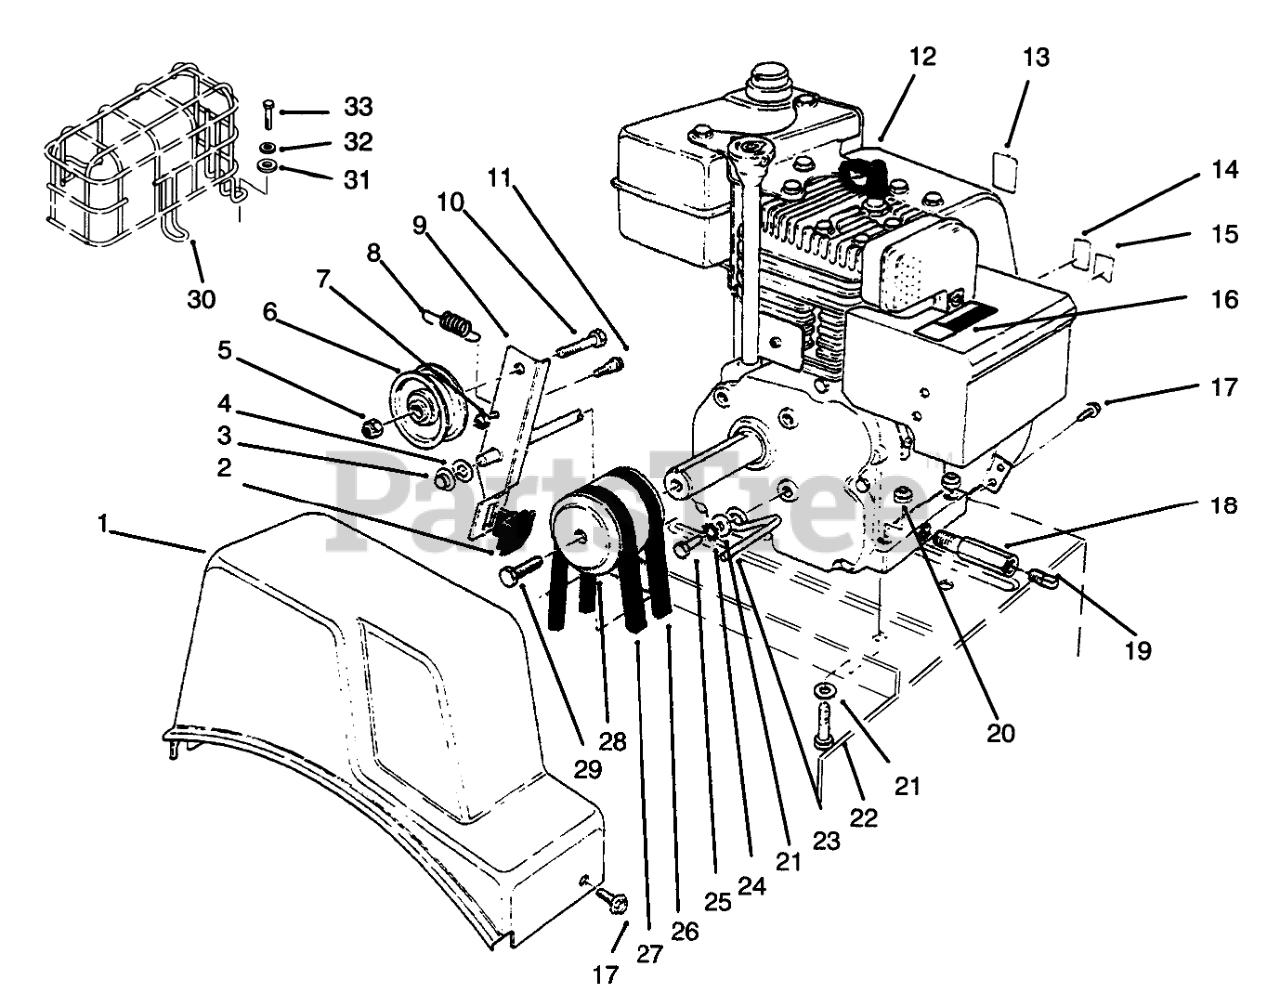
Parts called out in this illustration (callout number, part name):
1	COVER-BELT
2	PAD-BRAKE
3	NUT-LOCK, NI
4	WASHER-FLAT
5	RETAINER-PUSH ON
6	PULLEY-IDLER
7	NUT-LOCK, NI
8	SPRING
9	Auger Clutch (Incl. Ref. #2)
10	SCREW-HH
11	BOLT-SHOULDER
12	ENGINE
13	DECAL - PRIMER
14	THROTTLE DECAL, INT'L
15	CHOKE DECAL
16	DECAL-WARNING, HOT SURFACE
17	SCREW-HWH
18	PIPE-NIPPLE
19	CAP-PIPE
20	NUT-LOCK, NI
21	WASHER-PLAIN
22	SCREW-HH
23	RETAINER-BELT
24	WASHER-LOCK
25	SCREW-HH
26	V BELT-3L, TRACTION
27	V-BELT (29.50 INCH)
28	PULLEY-ENGINE
29	SCREW-SPECIAL
30	Guard-Muffler Model 38054
31	Washer-Flat
32	Washer-Lock
33	Screw
